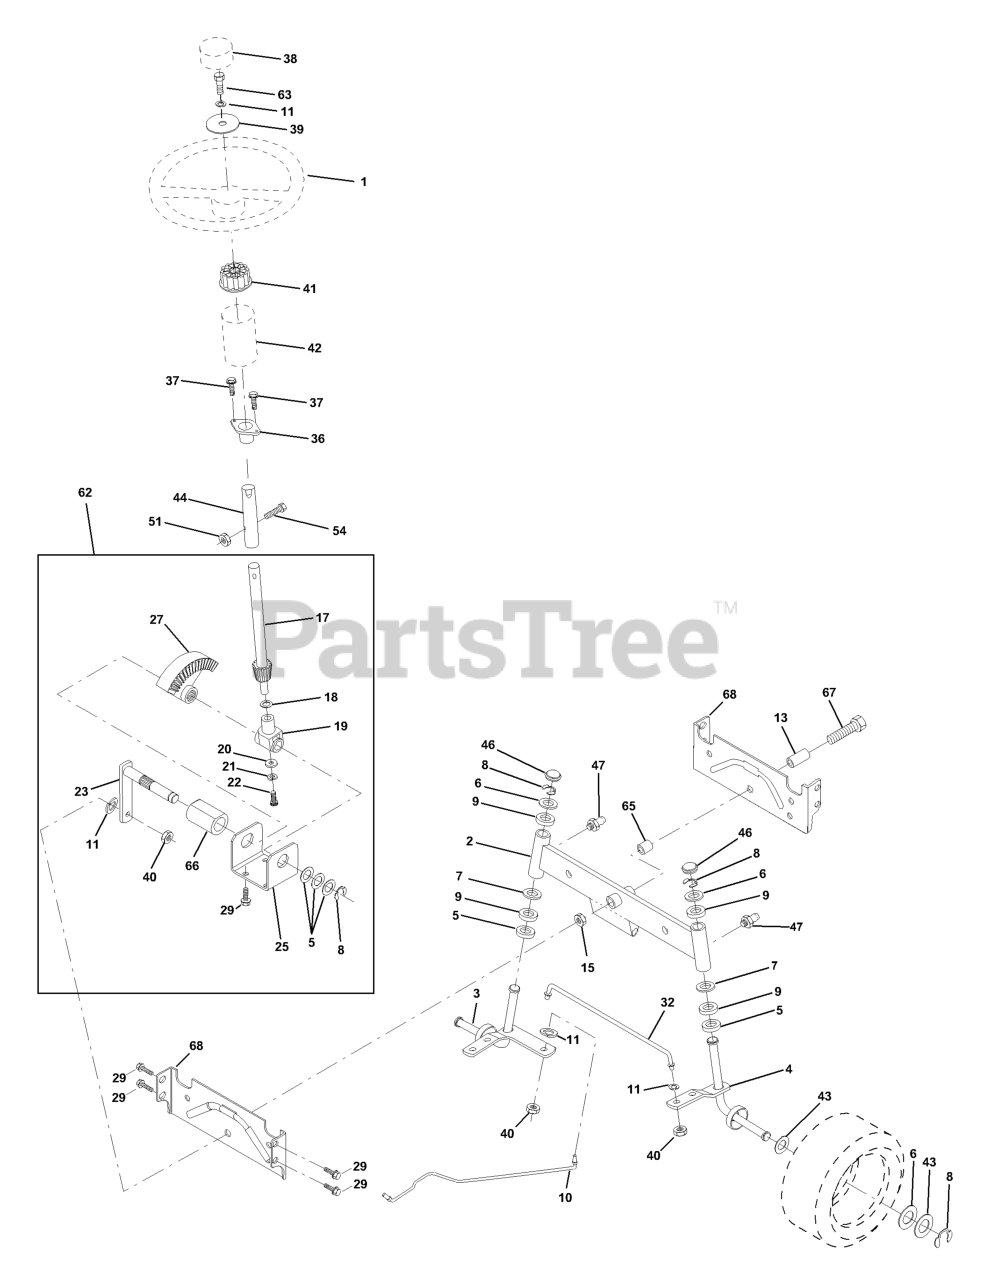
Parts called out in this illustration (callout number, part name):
1	STEERING WHEEL
2	FRONT AXLE ASSY
3	SPINDLE ASS'Y LH
4	SPINDLE ASM RH
5	THRUST WASHER
9	BRNG T
10	LINK.DRAG.DROPPED.LT
11	WASHER, LOCK 3/8
13	BEARING AXLE
15	NUT-LOC,FLANGE LT
17	SHAFT ASM STEERING
18	THRUST WASHER
19	SHAFT,SUPPORT
20	WASHER
21	LOCKWASHER
22	SCREW
23	SHAFT PITMAN
25	BRACKET STEERING
27	GEAR.SECTOR
29	SCREW
32	ROD ASSY/TIE BALL
36	BUSHING, STEERING
37	SCREW.TT.#10-32X.5.3/8.FLANGE
38	INSERT,STR WHEEL
39	WASHER T
40	GRIPCO NUT
41	ADAPTER LT
42	BOOT, STEERING
44	EXT SHAFT STEERING
46	CAP.SPINDLE.BLACK
47	ZERK M
51	NUT.71038.31-18.HEX.NYLOCK
54	BOLT.5/16-18X1-1/4 FULL.THREAD
62	KIT, STEERING ASSEMBLY
63	BOLT
65	SPACER AXLE
66	BEARING ARM
67	Bolt, Fin Hex 5/8-11 UNC x 2-3/4
68	AXLE, BRACE
